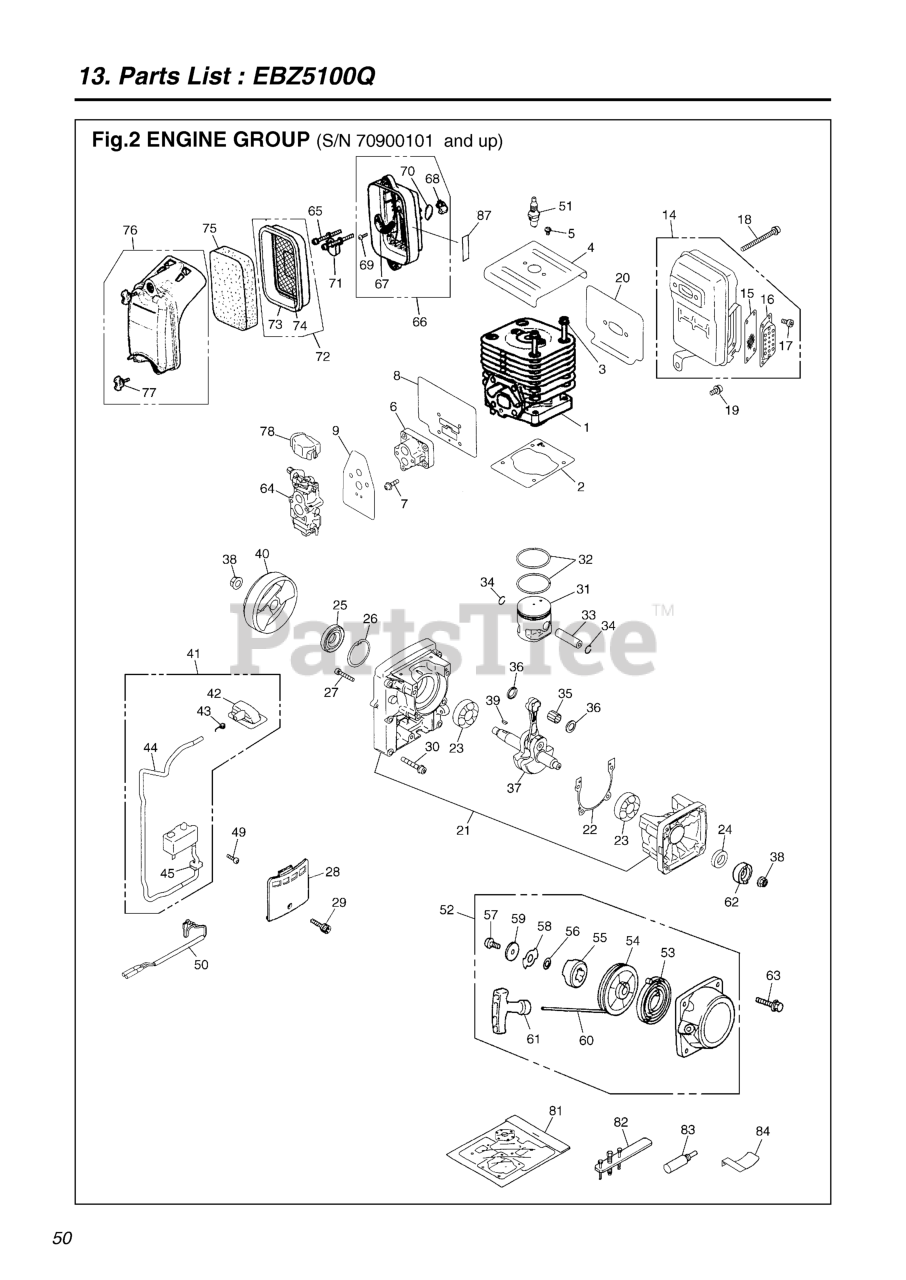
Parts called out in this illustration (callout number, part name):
1	CYLINDER
2	GASKET, BASE
3	BOLT TORX
4	PLATE, CYL
5	SCREW TORX
6	INSULATOR
7	BOLT TORX
8	GASKET, INSU
9	GASKET, CARB
14	MUFFLER ASSY
15	ARRESTER
16	DIFFUSER
17	Bolt
18	BOLT TORX
19	BOLT TORX
20	GASKET, MUFFLER
21	CRANKCASE COMP
22	GASKET, CASE
23	BEARING
24	SEAL
25	SEAL
26	SNAP RING
27	BOLT TORX
28	COVER
29	BOLT TORX
30	BOLT TORX
31	PISTON
32	RING
33	PIN
34	SNAP RING
35	BEARING
36	WASHER
37	CRANKSHAFT COMP
38	NUT
39	KEY
40	ROTOR
41	COIL ASSY.
42	CAP
43	SPRING
44	TUBE
45	GROMMET
49	BOLT TORX
50	CORD COMP
51	SPARK PLUG
52	RECOIL ASSY
53	SPRING
54	REEL
55	DOG
56	WASHER
57	SCREW
58	RETAINER
59	WASHER
60	ROPE
61	KNOB
62	PULLEY
63	BOLT, TORX
64	CARBURETOR ASSY
65	BOLT TORX
66	BODY ASSY
67	PLATE,CHOKE
68	LEVER
69	SCREW
70	O-RING
71	PLATE
72	PACKING COMP
73	PACKING
75	ELEMENT
76	COVER ASSY
77	KNOB
78	COVER
81	GASKET KIT
82	PULLER ASSY
83	STOPPER
84	GAUGE
87	LABEL, CHOKE
